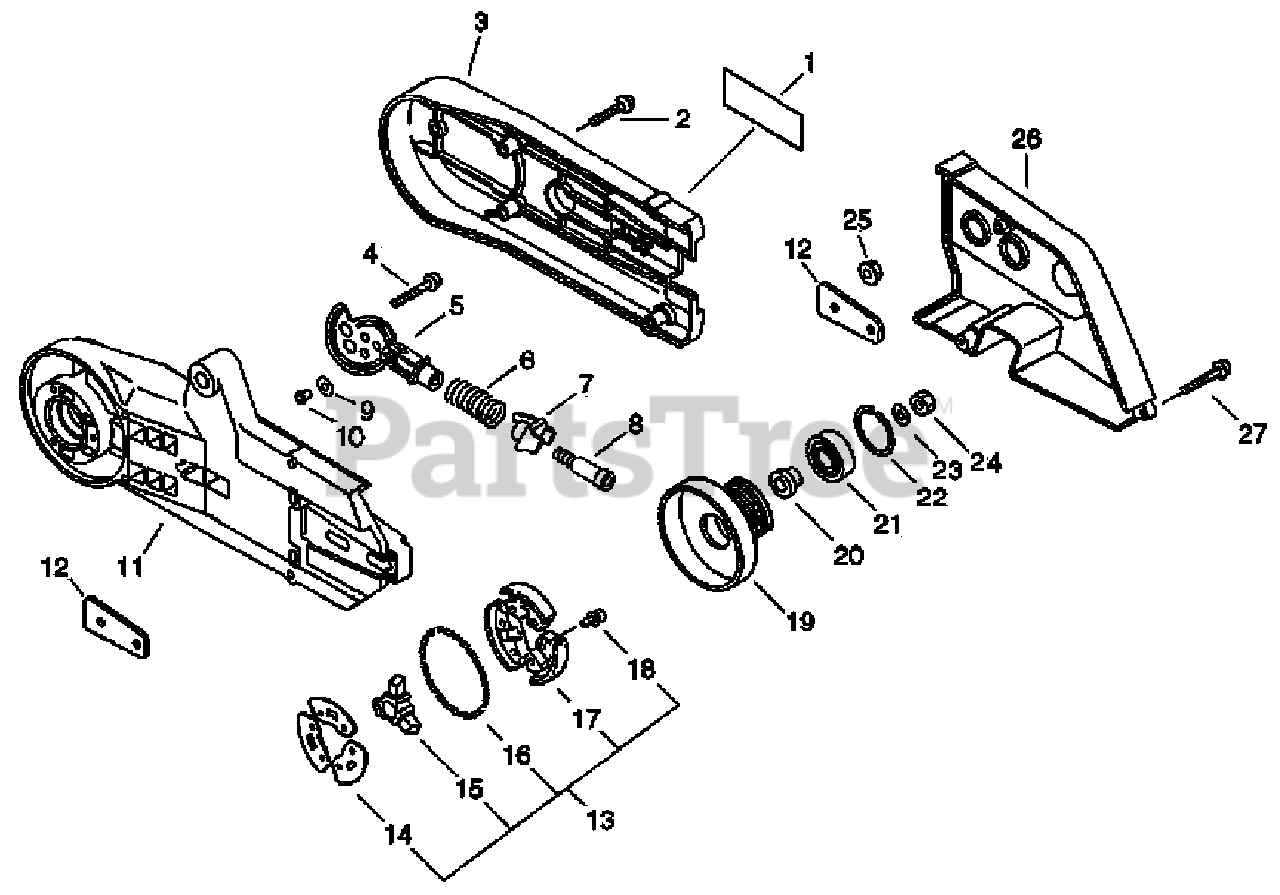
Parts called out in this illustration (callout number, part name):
1	LABEL - ECHO
2	SCREW 5×25
3	COVER, CUTTER ARM
4	BOLT 5×25
5	SHAFT, ARM ADJUST
6	SPRING, ADJUSTER
7	HOLDER, SPRING
9	WASHER, SPRING 8.5×16×0.5
11	ARM, CUTTER
12	SPACER, ARM
13	CLUTCH ASSY
14	PLATE, CLUTCH
15	BOSS, CLUTCH
16	SPRING, CLUTCH
17	SHOE SET, CLUTCH (3PCS)
18	BOLT 4×6
19	DRUM, CLUTCH
20	COLLAR - 10
21	BEARING, BALL 6001 DDU C3
22	RING, SNAP 28
24	NUT 8 LH
25	NUT, FLANGE M8×1.25
26	COVER, V-BELT
27	SCREW 5×25
